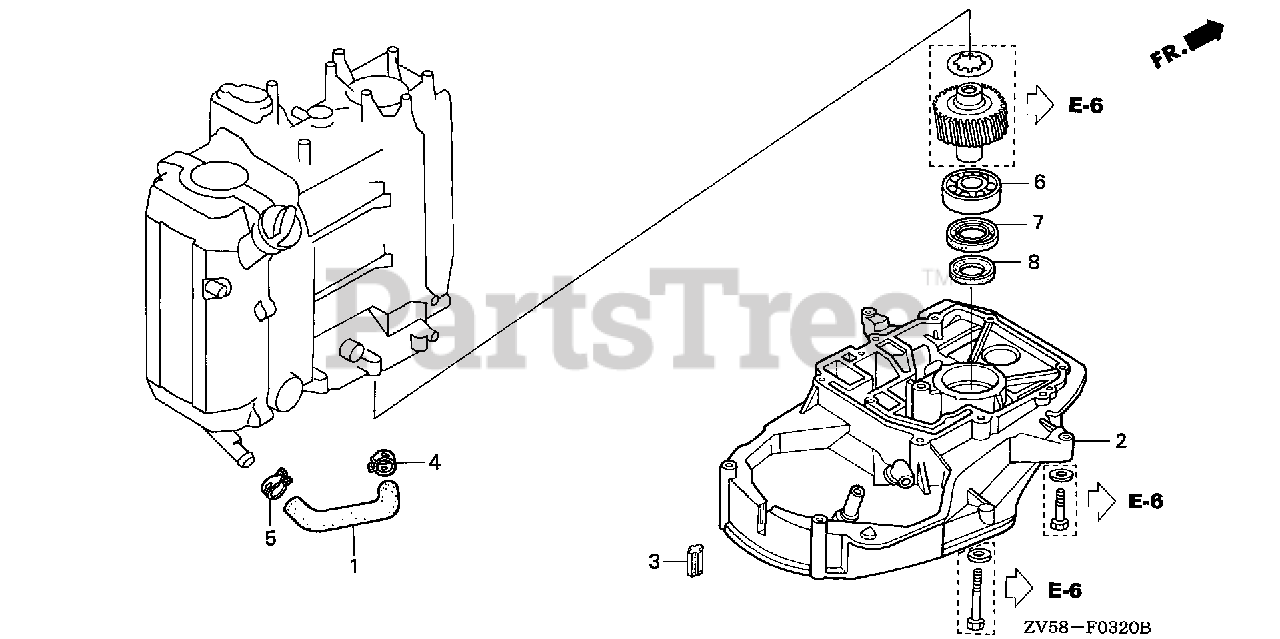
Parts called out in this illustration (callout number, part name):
1	TUBE SET, OIL
2	CASE KIT, PRIMARY GEAR *NH8* (DARK GRAY)
3	RUBBER, SEAL
4	CLAMP, TUBE (D18.8)
5	CLAMP, TUBE (D22)
6	BEARING, RADIAL BALL (6205)
7	OIL SEAL (25X40X7)
8	SEAL, WATER (17X26X7)
